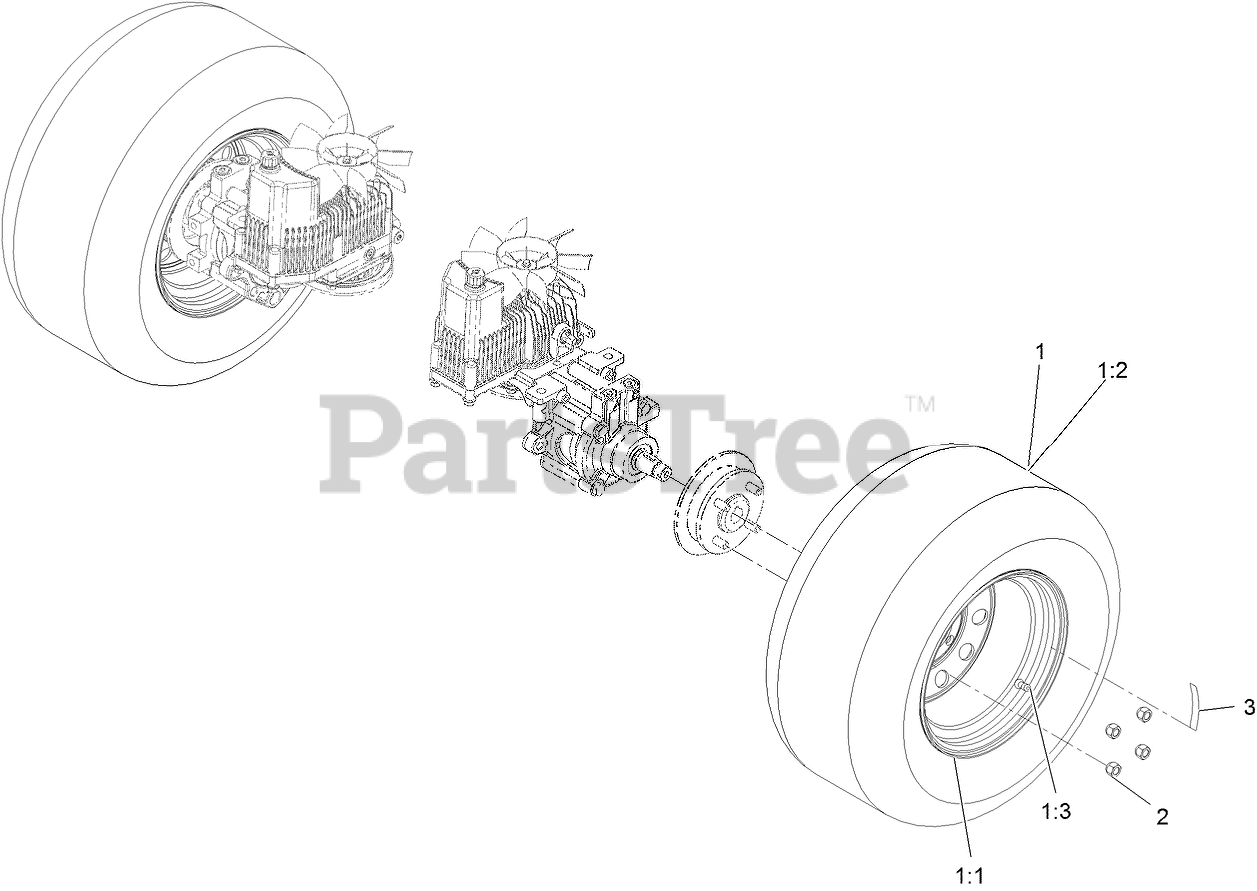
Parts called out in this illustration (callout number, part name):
1	ASM-WHEEL AND TIRE
1:1	ASM-RIM 72
1:2	TIRE-DRIVE
1:3	Stem-Valve
2	NUT-LUG
3	DECAL-TORQUE, WHEEL HUB LUG
